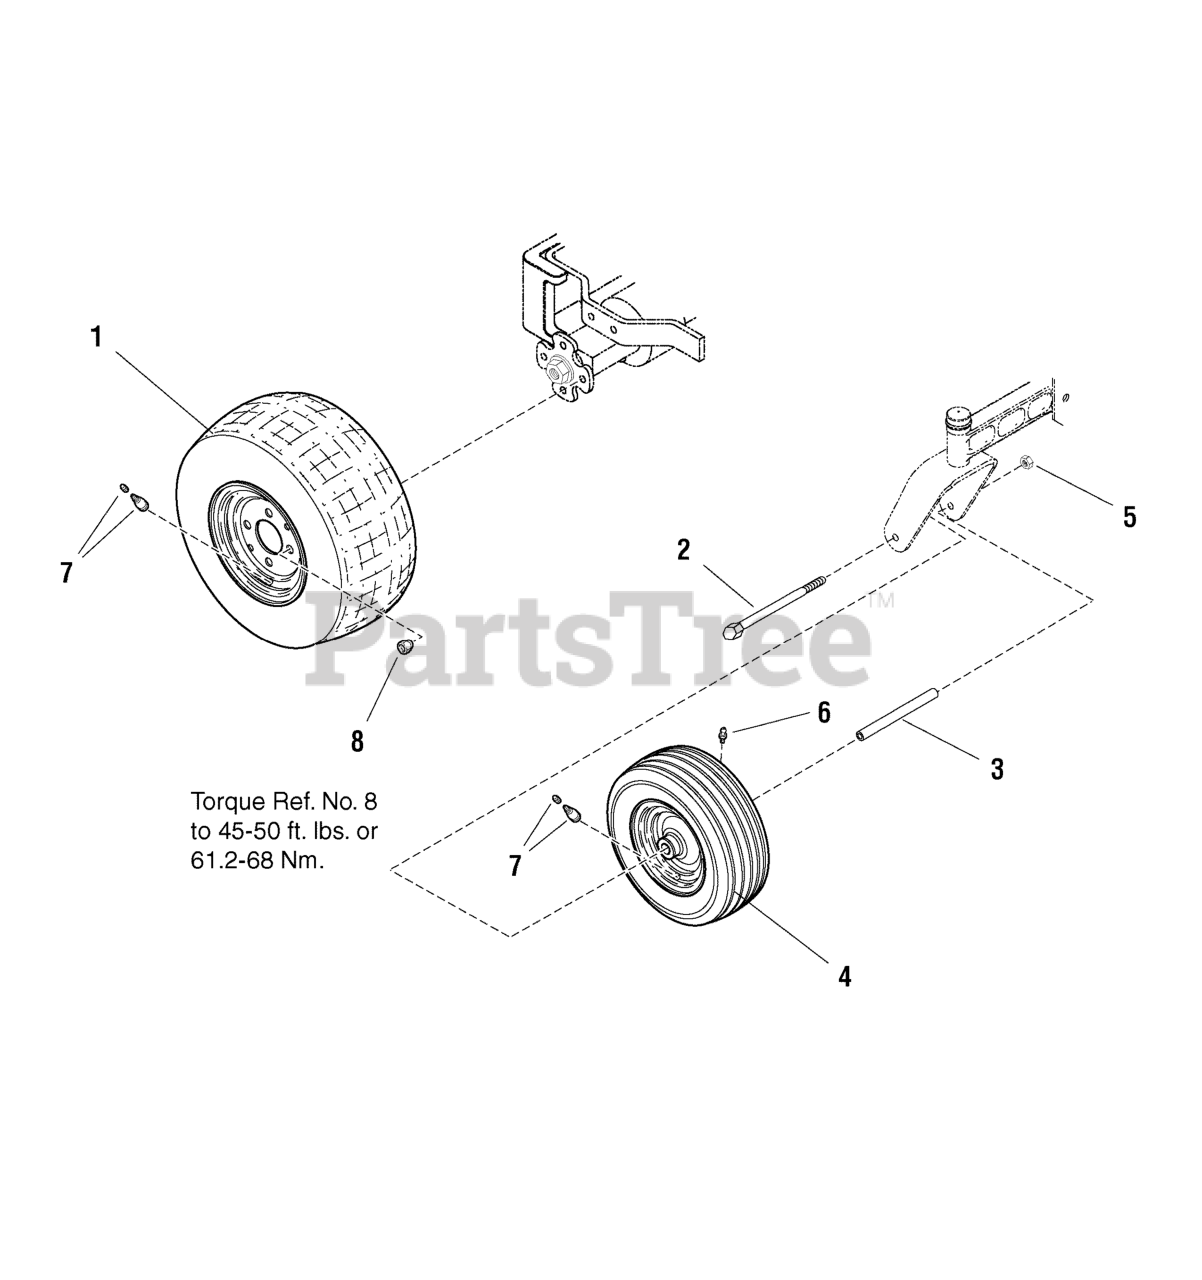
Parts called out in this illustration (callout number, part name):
1	WHEEL & TIRE ASSEMBLY, 18 x 8-1/2-8
2	CAPSCREW, Hex Head
3	TUBE, Caster Wheel
4	WHEEL & TIRE ASSEMBLY, 11 x 4-5
5	NUT, Hex Center Lock
6	FITTING, Lube
7	VALVE STEM & CAP
8	NUT, Hex Lug, 7/16-20
